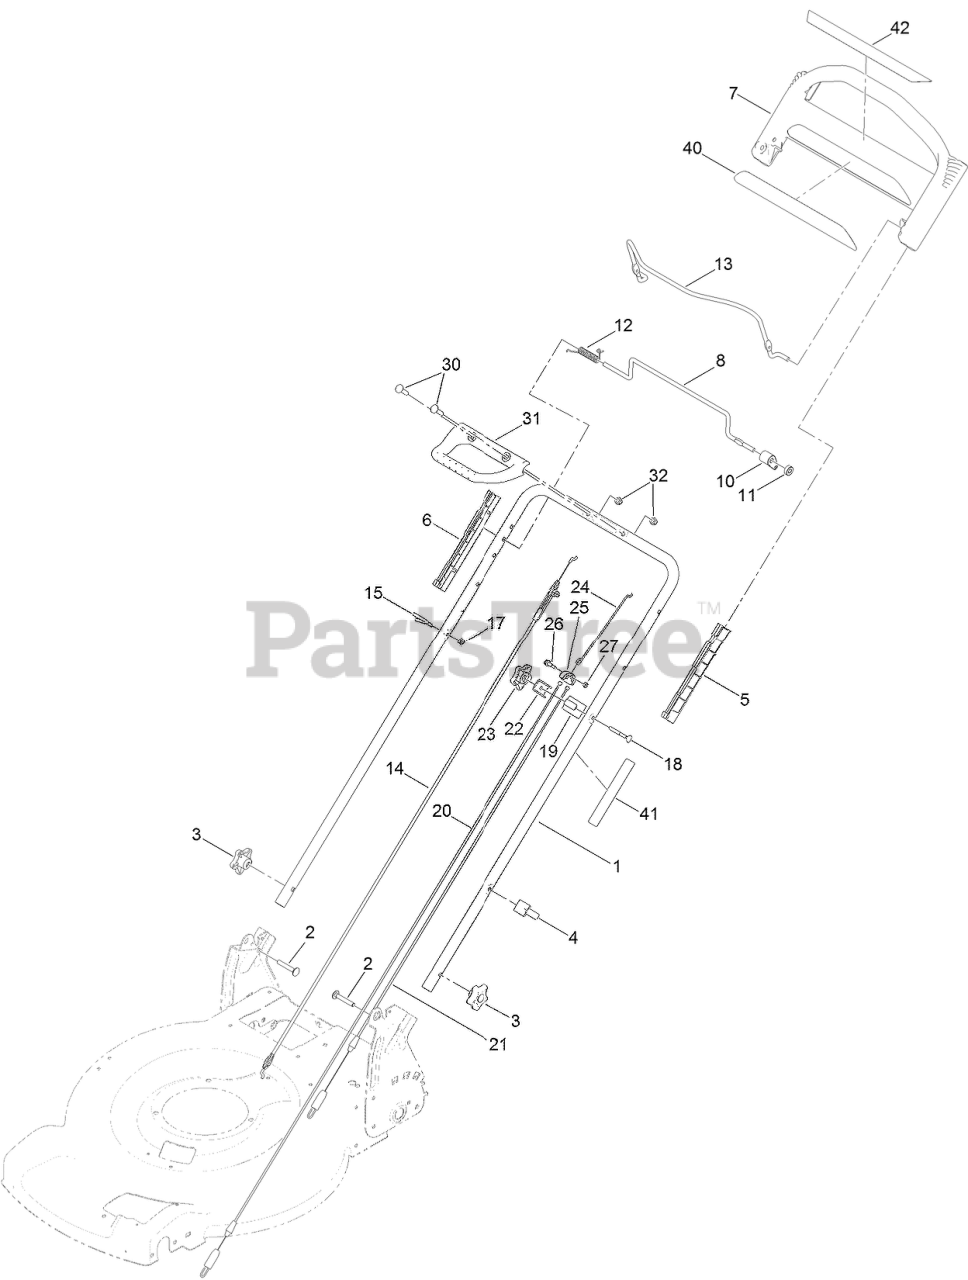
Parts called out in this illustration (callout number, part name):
2	Screw-CARR
3	KNOB-HANDLE
4	GUIDE-CABLE
5	GUIDE-LH
6	GUIDE-RH
7	HANDLE-CONTROL
8	BAR-CONTROL, TRACTION
10	LEVER-TRACTION
11	SPACER
12	Spring-Torsion
13	BAIL-BRAKE
14	CABLE-BRAKE
15	GUIDE-ROPE
17	NUT-LOCK, NI
18	SCREW-HANDLE
19	MOUNT-CABLE, TRACTION
20	CABLE-TRACTION, FRONT
21	CABLE-TRACTION, REAR
22	CLAMP-CABLE
23	KNOB-HANDLE, LOCKING
24	LINKAGE-EQUALIZER
25	YOKE-CABLE
26	SCREW-SHOULDER
27	NUT-LOCK, NI
30	BOLT-CARRIAGE
31	HANDLE-ASSIST, TRACTION
32	NUT-ACORN
41	DECAL-TRACTION, ADJUST
42	DECAL-ASSIST, TRACTION
